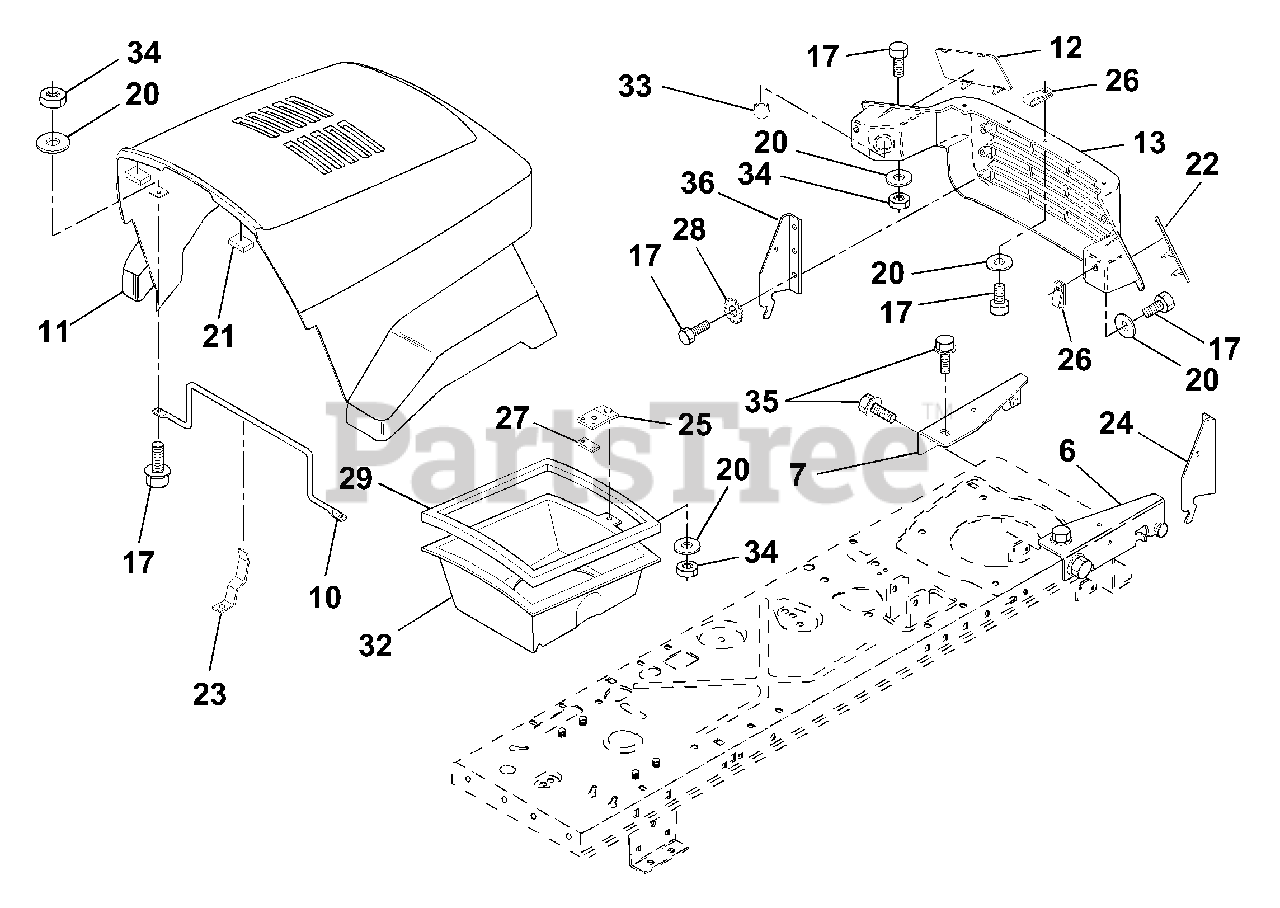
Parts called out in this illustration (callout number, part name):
6	Bracket Asm. Pivot Hood RH
7	Bracket Asm. Pivot Hood LH
10	Brace Hood
11	Hood
12	Lens LH
13	Grille
17	Bolt Fin Hex 1/4-20 x 5/8
20	Washer, Flat 1/4
21	Bumper Hood
22	Lens RH
23	Latch Hood
24	Bracket Pivot Hood RH
25	Clip Tinnerman
26	Clip Tinnerman
27	Clip Asm Duct
28	Washer Lock Ext. Tooth
29	Strip Foam
32	Duct, Air Hood
33	Plug Socket Light
34	Nut, Crownlock 1/4-20
35	Screw Thdrol 5/16-28 x 3/4
36	Bracket Pivot Hood LH
